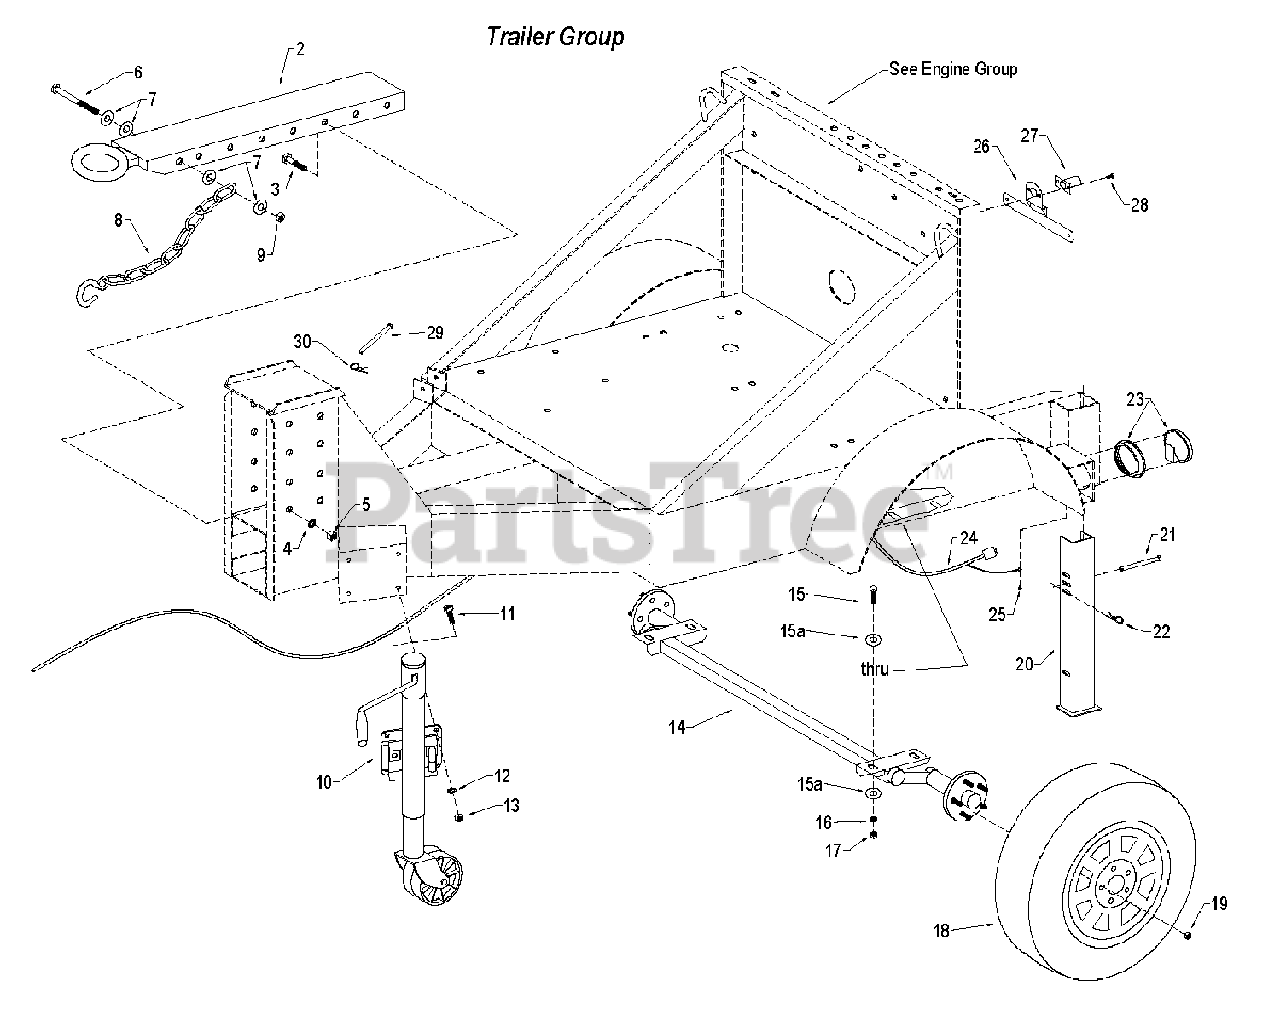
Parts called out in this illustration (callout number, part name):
1	Loader base and trailer frame (see engine group)
3	Bolt, hex - 1/2-13 x 1-1/4"
4	Washer, lock - 1/2
5	Nut, reverse lock - 1/2-13
6	Bolt, hex - 1/2-13 x 7"
7	Washer, flat - 1/2
8	Chain, safety towing
9	Nut, lock - 1/2-13
10	Jack, dual wheel support
11	Bolt, hex - 3/8-16 x 1"
12	Washer, lock - 3/8
13	Nut, lock - 3/8-16
14	Axle, Torflex
15	Bolt, hex, black oxide, 1/2-13 x 1-1/4 gr 5
16	Washer, lock - 1/2"
17	Nut, hex end lock – 1/2-13
18	Tire and wheel assy
20	Leg, support
21	Pin, clevis - 3/8 x 4-1/2"
22	Pin, bridge
23	Light, tail/stop assy
24	Harness, wiring
25	Screw, self-tapping - #10 x 1/2 (taillight ground)
26	Bracket, license
27	Light, license
28	Bolt, hex - 1/4-20 x 1 – bolts license light assy to frame
29	Pin, clevis - 3/8 x 4-1/2"
30	Pin, bridge
